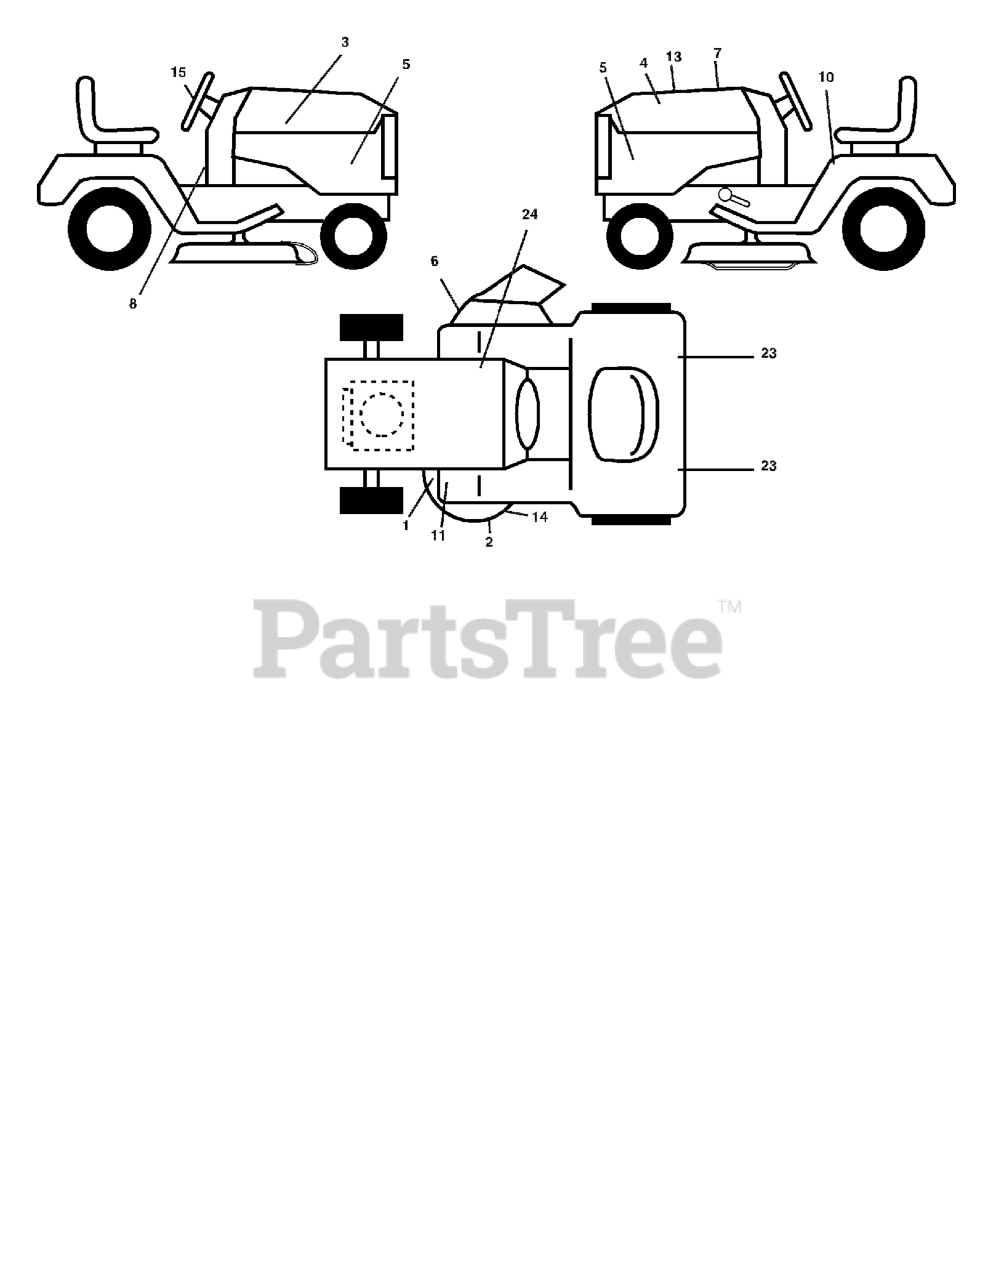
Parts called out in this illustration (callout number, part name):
1	DECAL CLUTCH/BRAKE
2	DECAL, MOWER HEAVY DUTY
3	DECAL
4	DECAL
5	DECAL
6	DECAL.WARN.KEEP.HAND.AWAY
7	DECAL HOOD CUST. RESP.
8	DECAL, SADDLE BRAKE PARKING
10	DECAL FENDER DANGER
11	DECAL, FOOTREST
13	DECAL
14	DECAL V-BELT SCHEMATIC
15	DECAL.STEERING.HUSQ.BLUE
23	REFLECTOR-TAIL YT
24	DECAL BTRY SYMBOLS
